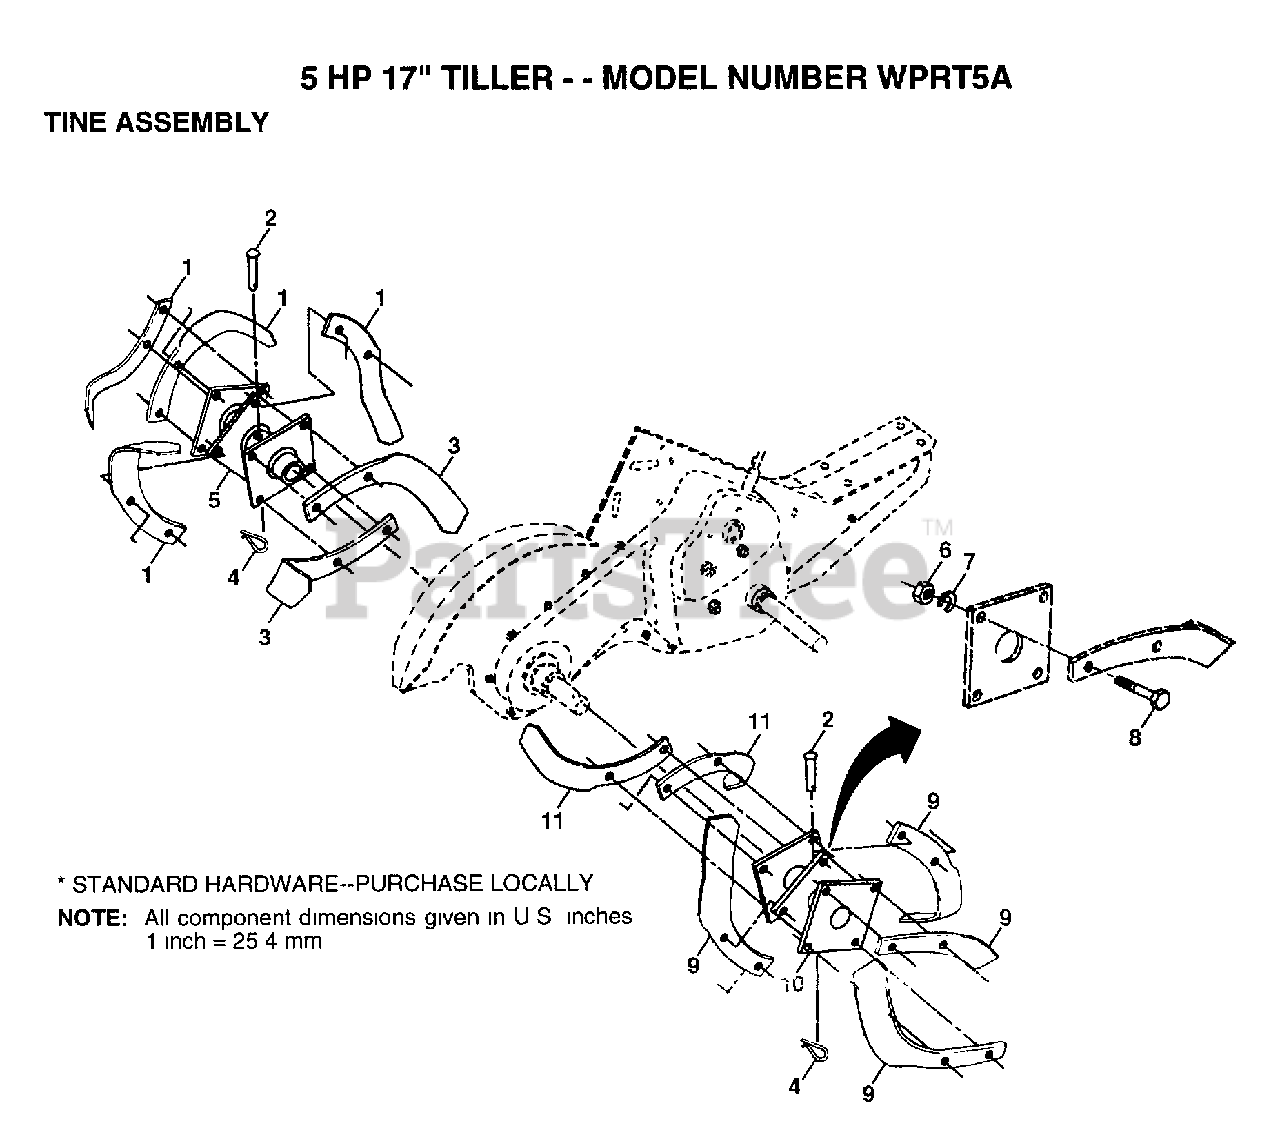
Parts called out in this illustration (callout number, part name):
2	PIN.CLEVIS.SHEAR
3	"TINE.LH.12"""
4	RETAINER.SPRING
5	HUB&PLATE ASM LH
7	LOCKWASHER
8	BOLT
10	HUB&PLATE ASM RH
11	"TINE.RH.12"""
